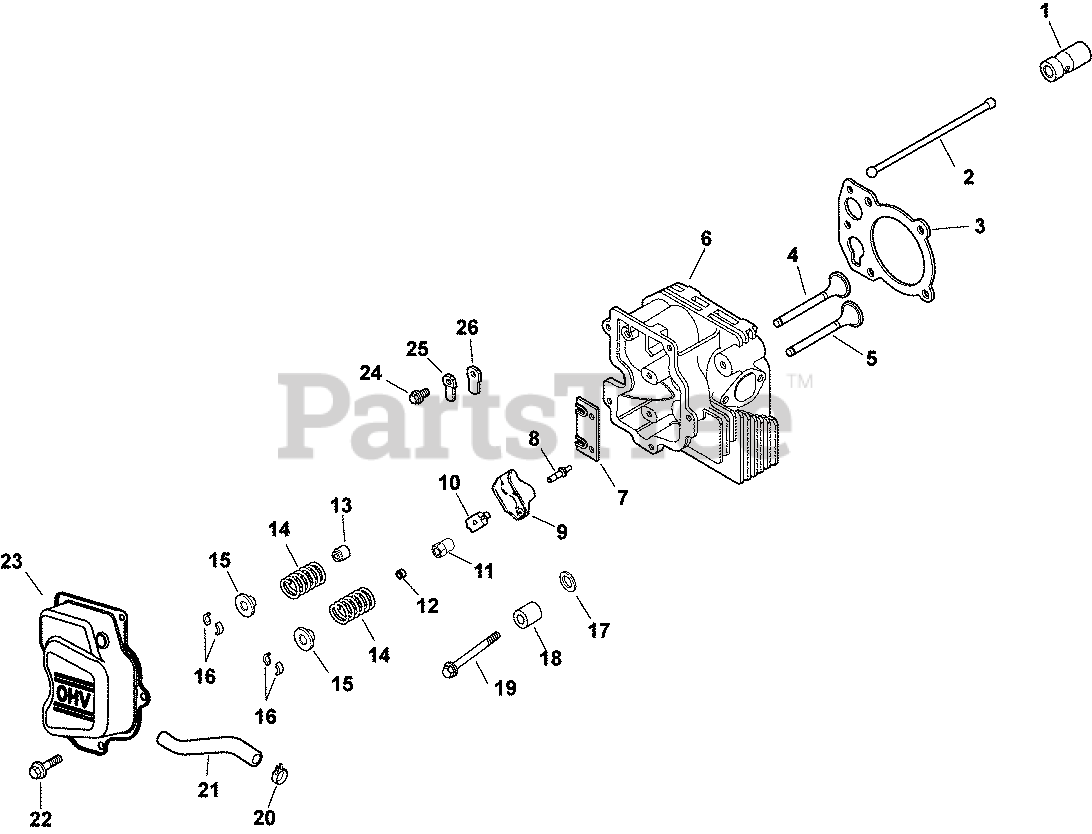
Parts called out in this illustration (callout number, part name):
1	LIFTER, HYDRAULIC VALVE-USE 25 351 10-S
2	ROD, PUSH
3	GASKET, CYLINDER HEAD
4	VALVE, INTAKE
5	VALVE, EXHAUST
6	KIT, HEAD, CYLINDER
7	PLATE, GUIDE - DISCONTINUED
8	STUD, ROCKER
9	ARM, ROCKER
10	PIVOT, ROCKER ARM
11	NUT, HEX (AVT)-USE 25 100 38-S
12	SCREW, SET (AVT)-USE 25 086 168-S
13	SEAL, VALVE STEM - (#2503214S)
14	SPRING, VALVE
15	RETAINER, VALVE SPRING - USE 25 173 28-S
16	KIT, RETAINER
17	WASHER, FLAT 13/32"
18	SPACER, HEAD BOLT EXHAUST PORT
19	SCREW, CYLINDER HEAD (M10 X 80)
20	CLAMP, HOSE (KM)-USE 25 237 31-S
21	HOSE, BREATHER - USE 12 326 30-S
22	SCREW,FLG THD FRM M6X1.0X16-(#25086397S)
23	COVER, ROCKER
24	SCREW, FLG THD FRM M5X.8X10
25	RETAINER, REED
26	REED, BREATHER
